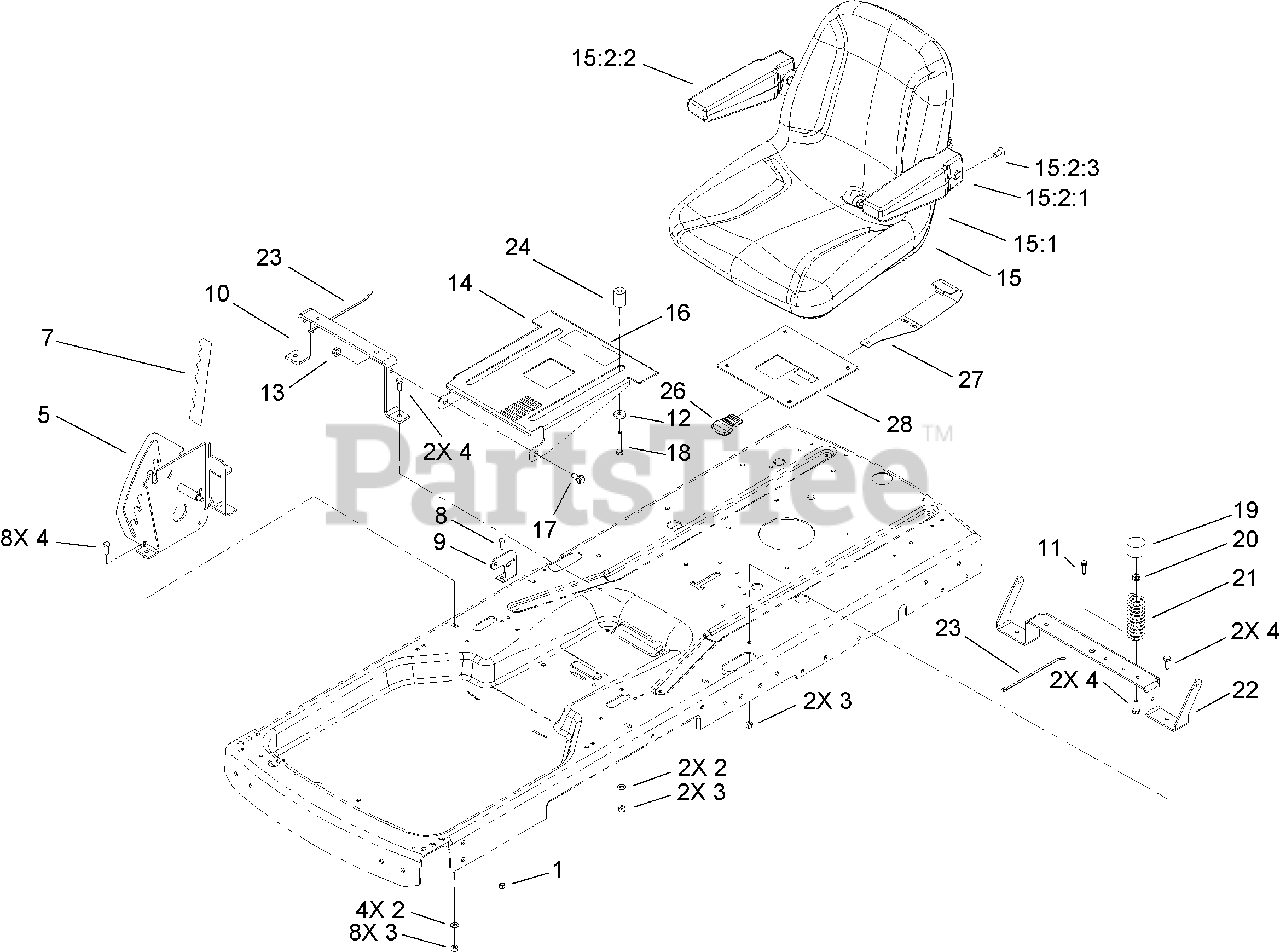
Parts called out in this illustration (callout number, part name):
1	NUT-LOCK, NI
2	WASHER-FLAT
3	NUT-LOCK, NI
4	SCREW-HH
5	RH PLATE ASM
7	DECAL-HOC
8	SCREW-HH
9	BRACKET-BELLCRANK
10	BRACE-SEAT, FRONT
11	SCREW-HWHTF
14	BRACKET-SEAT
15	SEAT ASM
15:2:1	LH ARMREST KIT
15:2:2	RH ARMREST KIT
15:2:3	SCREW-HSBH
16	DECAL-SERVICES
17	BOLT-SHOULDER
18	SCREW-HH
19	CAP-PROTECTOR
21	SPRING-COMPRESSION
22	BRACE-SEAT, REAR
23	STRAP-TIE
26	KNOB-LEVER, HOC
27	LATCH-SEAT
28	MOUNT-LATCH, SEAT
